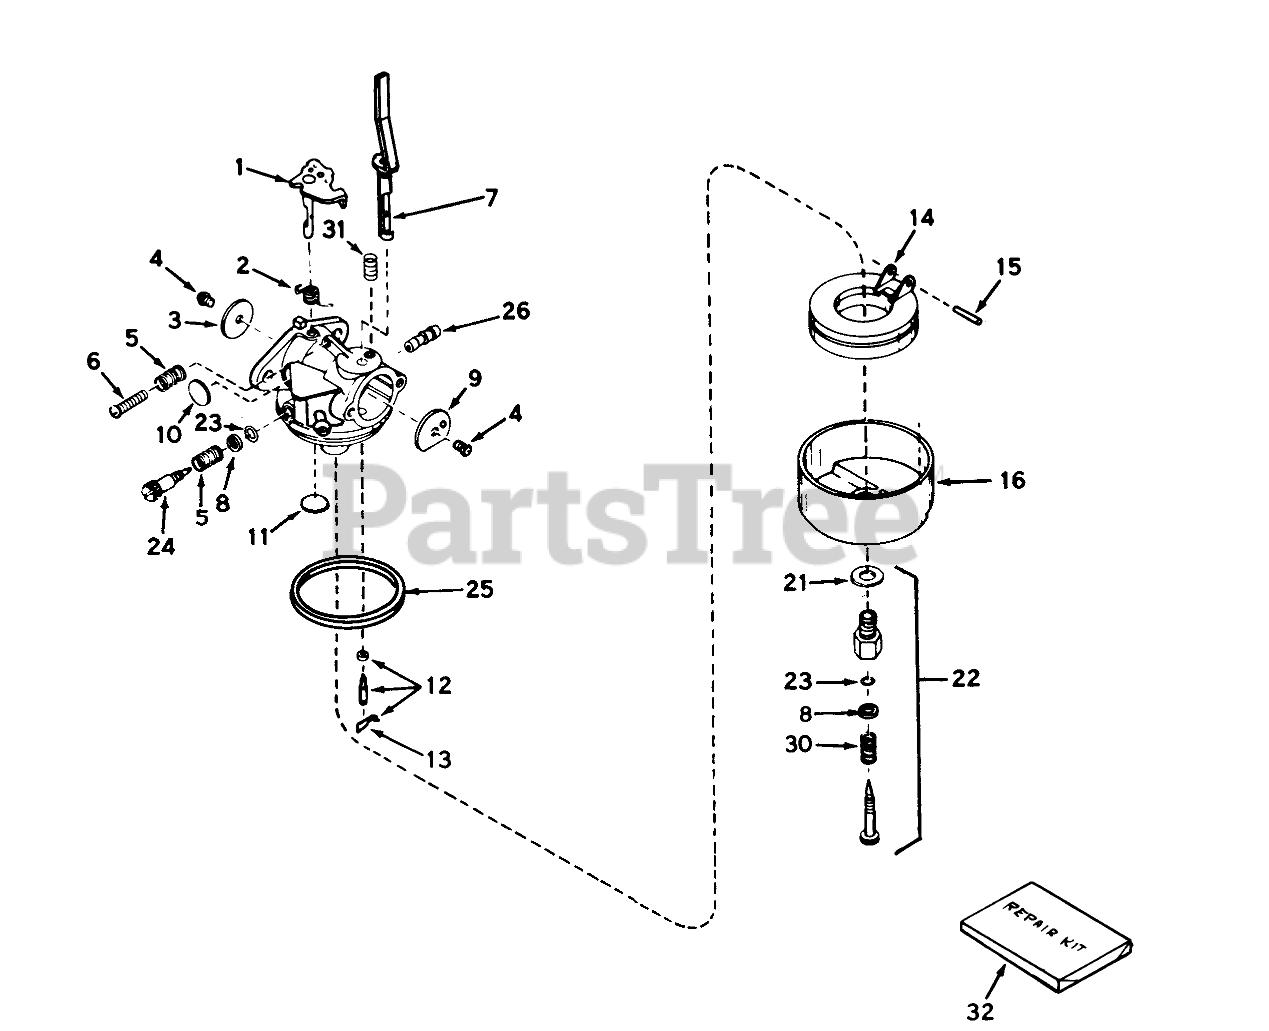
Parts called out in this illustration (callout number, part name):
1	Shaft/Lever-Throttle
2	Spring, Return
3	Shutter-Throttle
4	Screw-Shutter
5	Spring-Tension
6	Screw-Throttle Crack Screw / Idle Speed
7	Shaft & Lever Assy., Choke
9	Shutter-choke
10	Plug-Welch, Idle Mixture Well
11	Plug-Welch, Atmospheric Vent
12	Inlet Needle, Seat & Clip Assy. (Incl. Ref. #13)
13	Clip-Spring
14	Float
15	Shaft-Float
16	Bowl-Float (no drain)
21	Washer-Bowl Nut
22	Adjustment Screw Assy., Main (Incl. Ref. #8, 21, 23 & 30)
23	"O"Ring
24	Screw, Idle Adj.
25	O Ring-Bowl, Float
26	Fuel Fitting
31	Spring-Positioning, Choke
32	Kit-Repair
